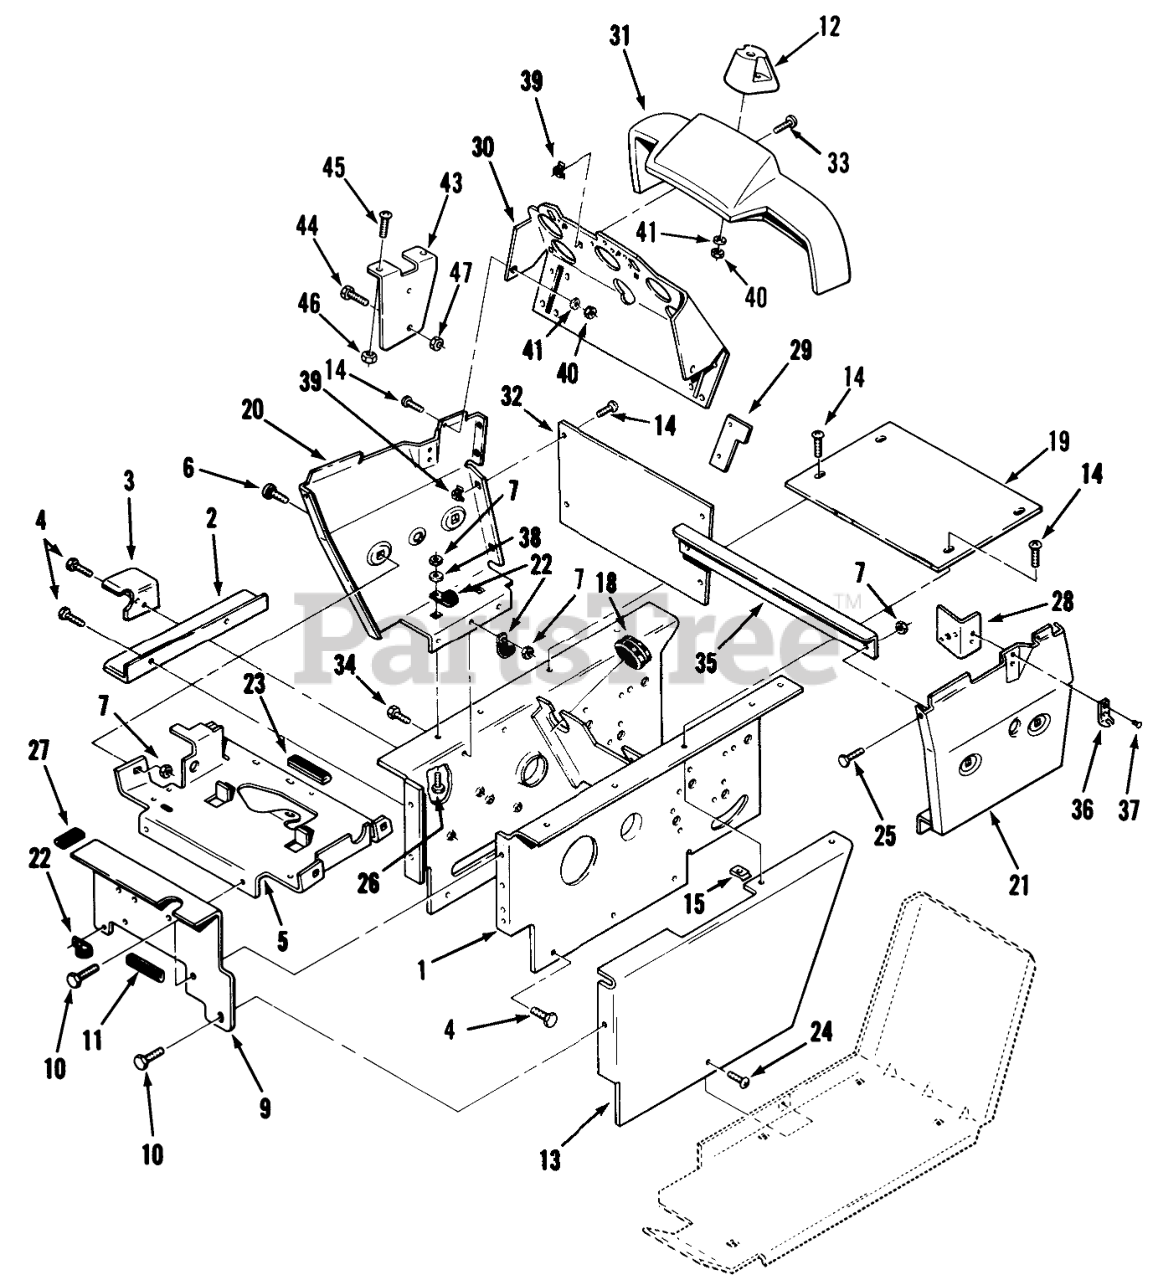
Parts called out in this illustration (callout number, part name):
1	Hoodstand
2	ANGLE-BELT GUARD B
3	Belt Bracket
4	SCREW
5	WLD-SUPPORTB
6	Bolt
7	NUT-LOCK, NI
9	PLATE-FRT HOODSTA B
10	SCREW
11	EDGE TRIM 2" 102896
12	COVER-STEERING SHAFT
13	COVER-L.H. R
14	SCREW-PPH
18	GROMMET
19	Plate-Top Hoodstand
20	Panel-RH
21	LS Panel
22	CLIP
23	EDGE TRIM 5" OF 102896
24	Screw
25	H H C S
26	CARRIAGE BOLT -4
27	EDGE TRIM-BULK
28	BRACKET-SWITCH SU
29	STOP-CHOKE
30	ASM-Panel
31	Kit-Console Cover (Contains #115620 5-Gauge Cover, #118410 Steering Cover, (4) 118780 Screw #6 Plastite, & (4) 920270 Washers)
32	Plate-Hoodstand
33	Screw
34	Bolt
35	STIFFENER-PANEL B
36	Latch Keeper (Included in 106825 Hood Latch)
37	RIVET
38	WASHER-PLAIN
39	NUT-RETAINED
40	NUT-LOCK, NI
41	WASHER-FLAT
43	Bracket-Holder
45	H H C S
46	Nut
47	NUT-LOCK, NI
